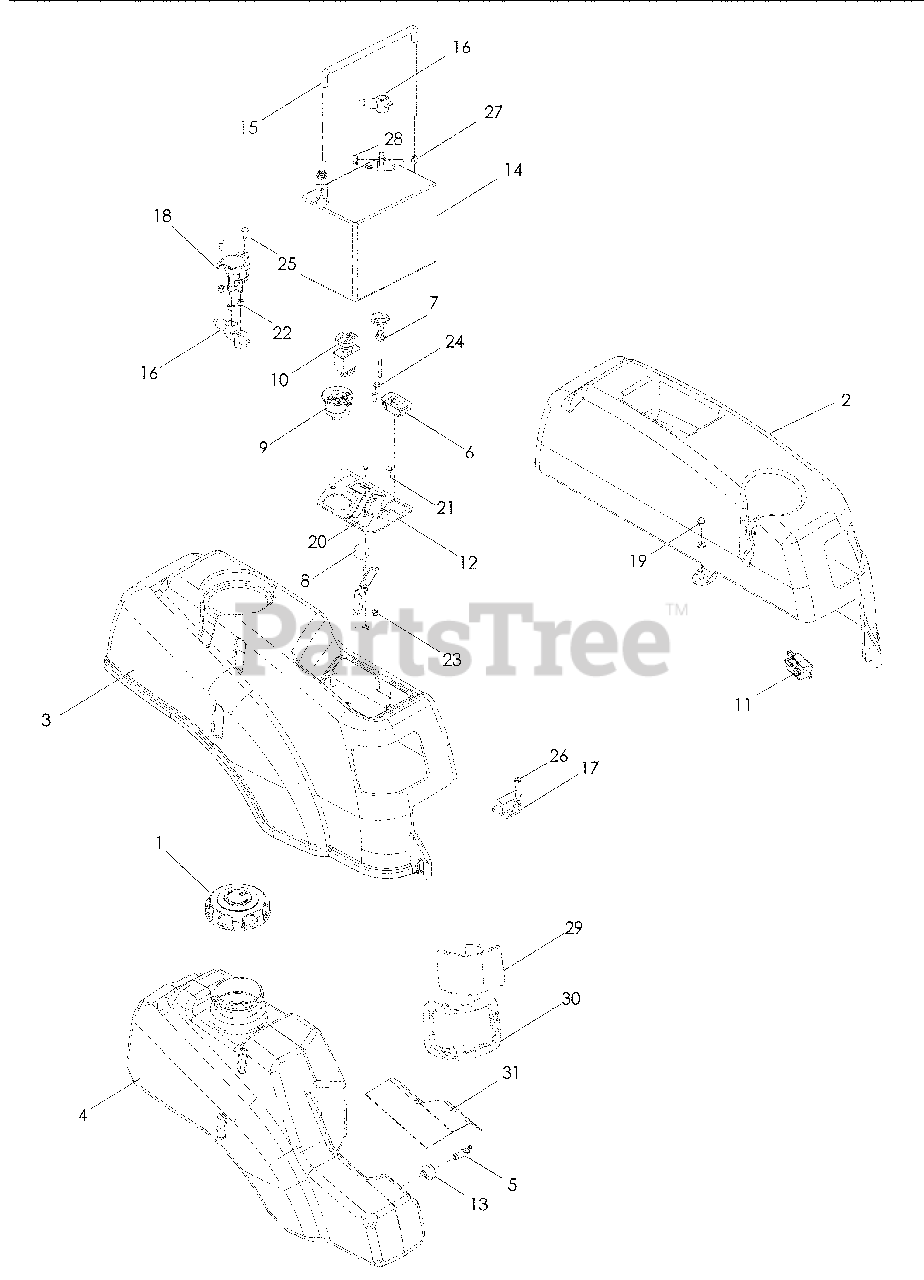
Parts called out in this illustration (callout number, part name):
2	FENDER, LT
3	FENDER, RT
4	TANK, FUEL
5	ELBOW, TANK
6	HOUR METER
7	CONTROL, CHOKE
8	CABLE, THROTTLE EZ4824, EZ5221, EZ5226
9	CABLE, THROTTLE EZC4824, EZ4824K, EZ5224, EZ6124
10	SWITCH, IGNITION
11	SWITCH, CLUTCH
12	SWITCH, BRAKE
13	PLATE, CONTROL
14	GROMMET, RUBBER
15	BATTERY
16	TIE DOWN, BATTERY
17	TERMINAL COVER
18	SWITCH, NC
20	BOLT ¼-20 x ½ HWST
21	DECAL, CONSOLE
22	SCREW 10-24 x ½ SLT HD
23	NUT ¼-20 HEX NYLOC
24	NUT 10-24 HEX NYLOC
25	SCREW 10-12 x ¾ WSH HD
26	SCREW ¼-20 x 5/8 BTN SKT
27	SCREW 10-24 x 5/8 WSH HD
28	RHSNB 5/16-18 x ¾
29	NUT 5/16-18 HEX WHIZLK
30	LENS, LT
31	LENS, RT
